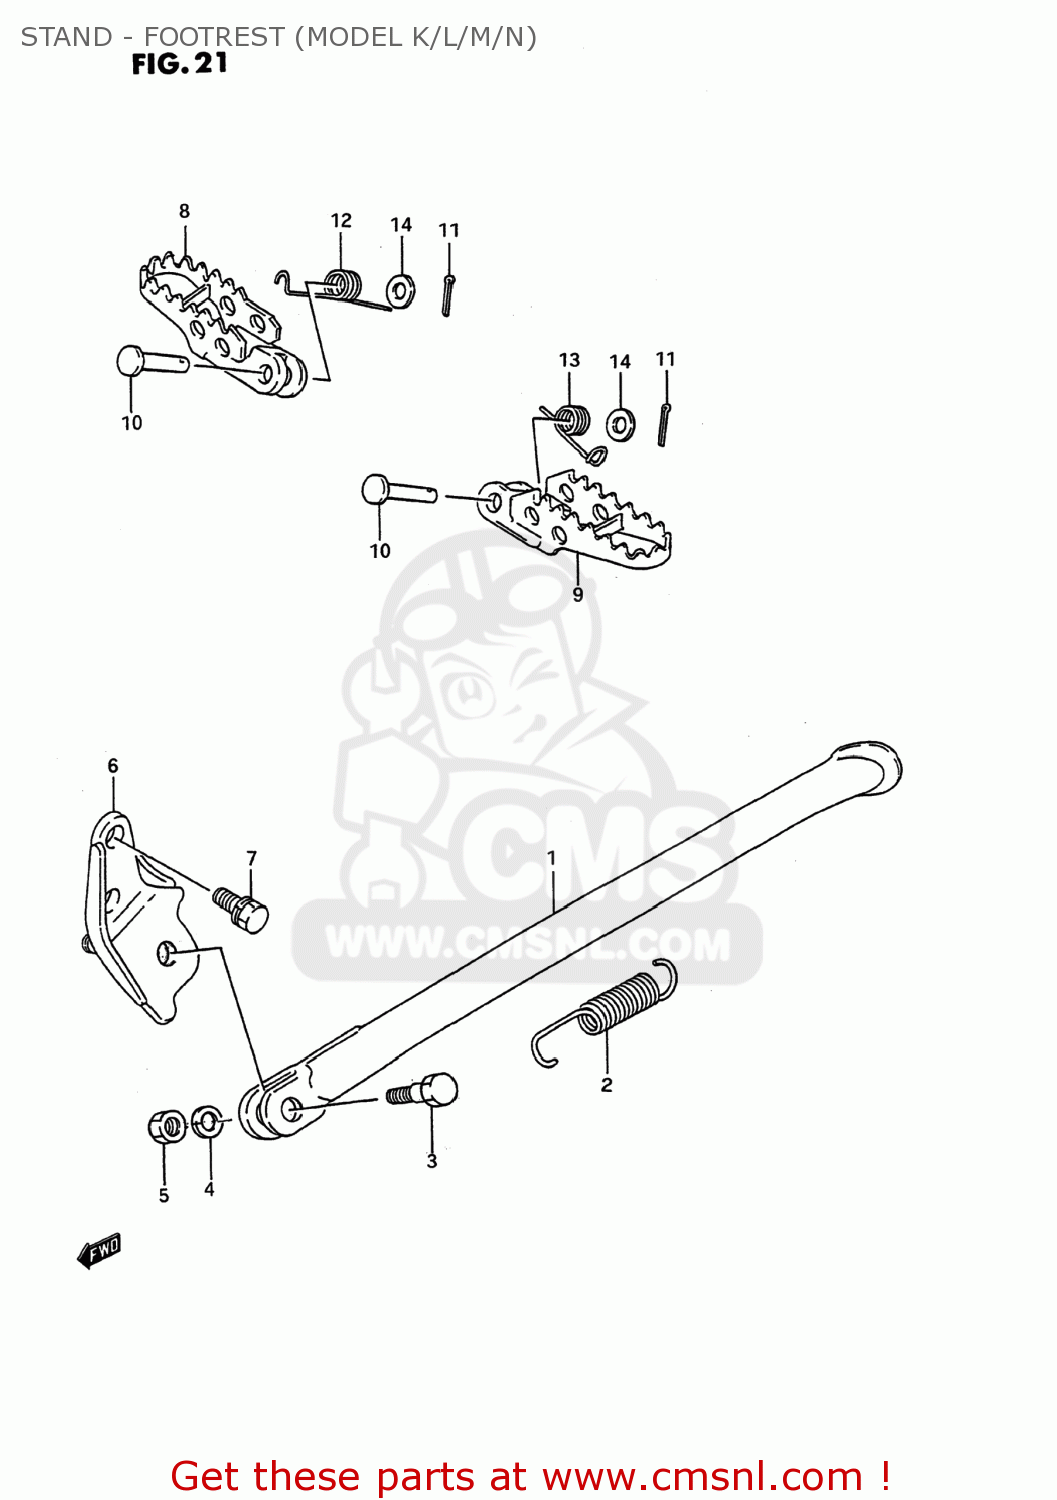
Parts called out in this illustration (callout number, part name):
1	STAND,PROP(BLUE)
2	SPRING
3	BOLT L:30
4	WASHER,LOCK
5	NUT
6	BRACKET,PROP STAND(BLUE)
7	BOLT
8	FOOTREST,FRONT,RIGHT
9	FOOTREST
10	PIN
11	PIN 25X20
12	SPRING
13	SPRING
14	WASHER
